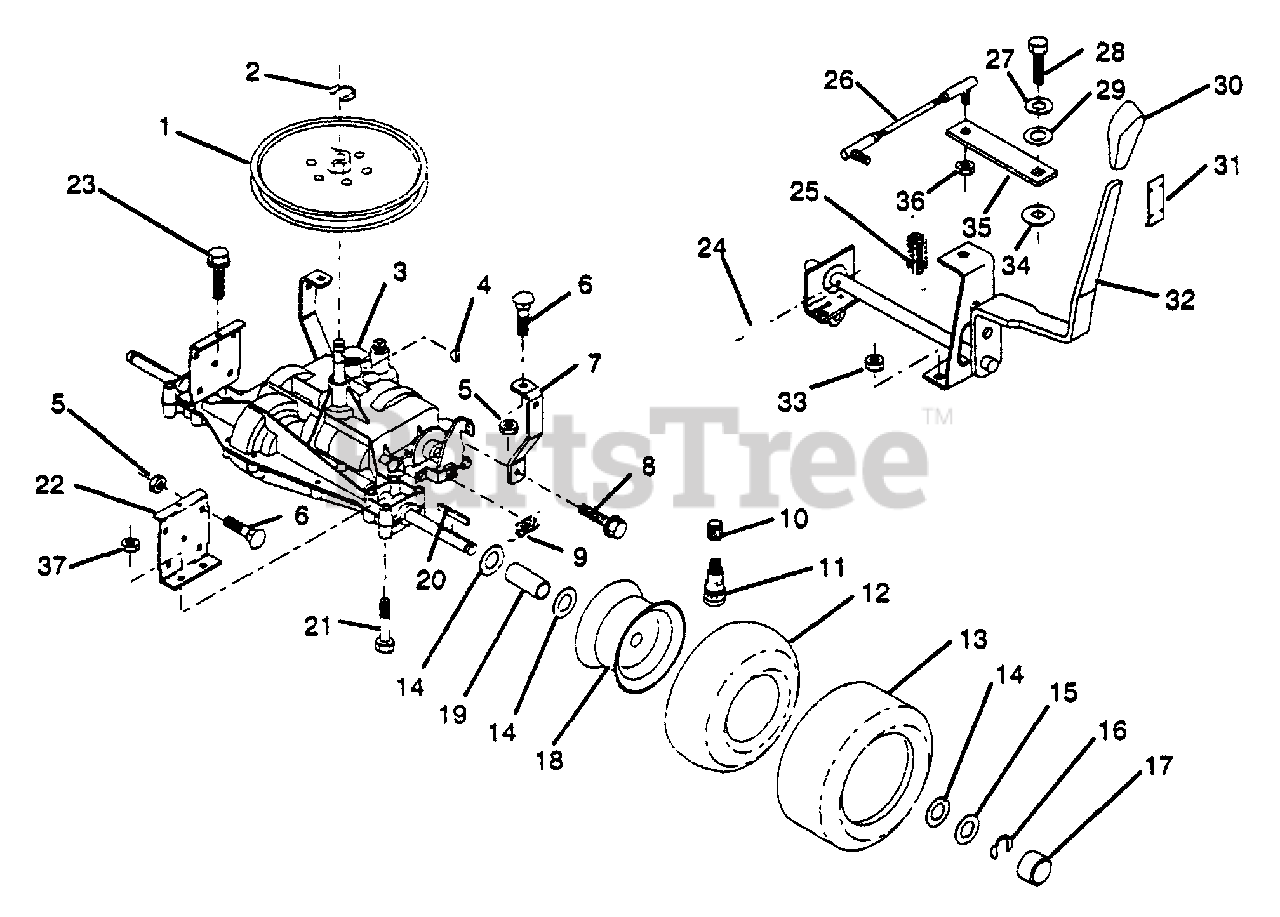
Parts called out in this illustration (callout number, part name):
2	Ring, Retainer
3	Transaxle, Foote Dana, 6 Speed
4	Key, Woodruff #9
5	Nut, Crownlock 5/16-18
6	Bolt, Carriage 5/16-18 UNC x 3/4
7	Strap, Torque
8	Screw, Hex Thdrol. 5/16-18 x 1/2
9	Spring, Brake
10	Cap, Valve
11	Stem, Valve
13	Tire, Rear
14	Washer 25/32 x 1-1/4 x 16 Ga.
15	Washer 25/32 x 1-5/8 x 16 Ga.
20	Key, Square
21	Bolt, Fin, Hex 3/8-16 UNC x 2-3/4
22	Bracket, Transaxle
23	Screw, 5/16-18 x 3/4
24	Pin, Cotter 1/8 X 1
25	Spring, Extension
26	Link, Shift
27	Washer, Lock Hvy. Helical Spring 1/4
28	Bolt, Fin, Hex 1/4-28 UNF x 3/4 Gr.8
29	Washer 9/32 x 3/4 x 10 Ga.
30	Knob, Shift Control
31	Retainer, Knob
32	Assembly, Shift Handle
33	Nut, Keps 5/16-18
34	Washer, Shift Plate
35	Arm, Shift
36	Nut, Hex Nylon 5/16-24
37	Nut, Crownlock 3/8 -16 UNC
